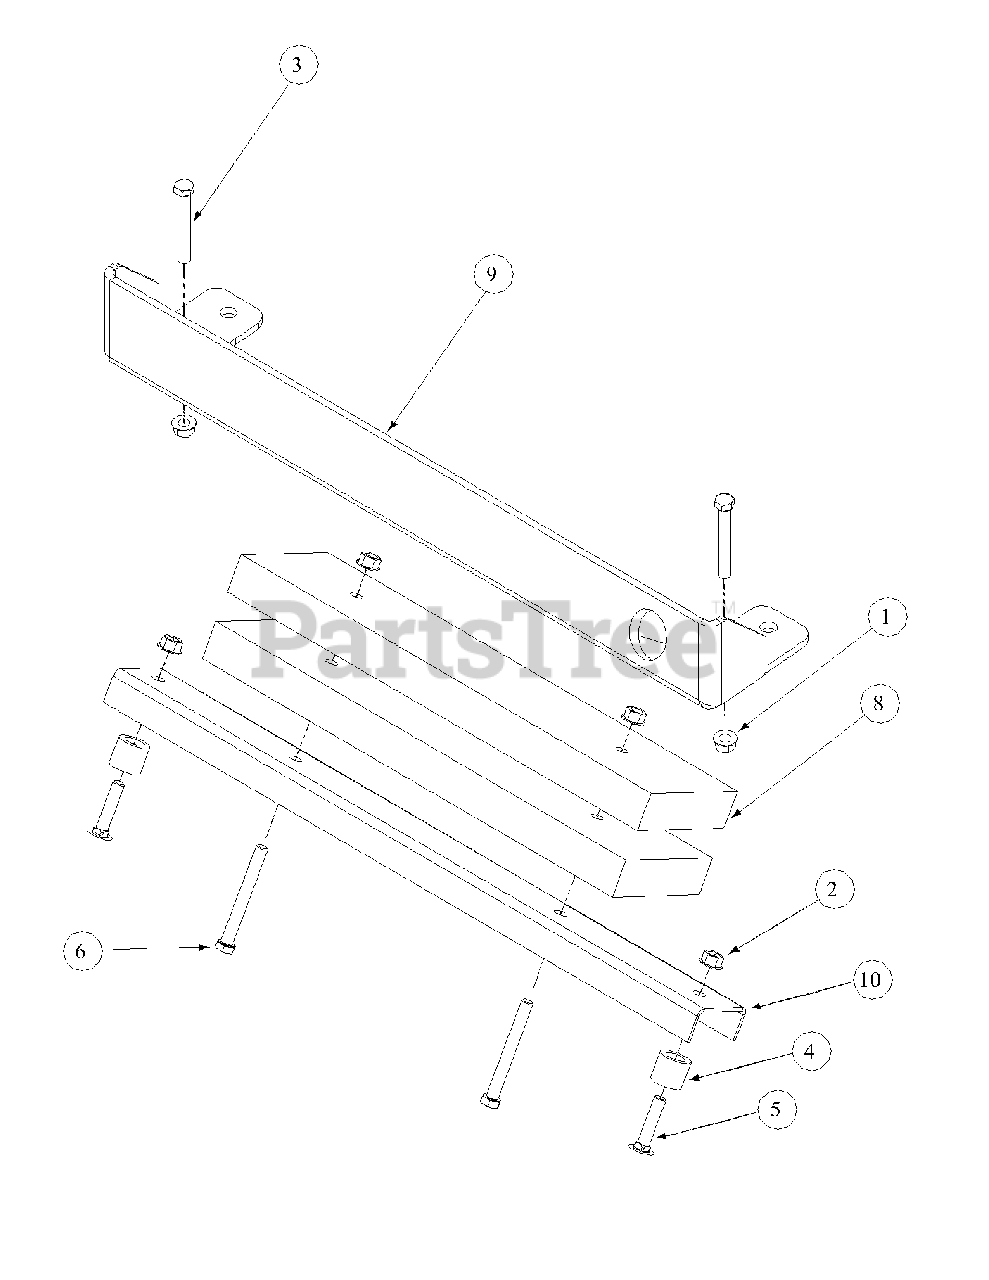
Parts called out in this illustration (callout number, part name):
1	Hex Nut, 1/2-13, Insert Lock
2	Nut, Hex 3/8-16 Flange Lock
3	HHCS, 1/2-13, 3.00
4	Spacer Crossbar
5	Carriage Bolt, 3/8-16, 1.75
6	HHCS, 3/8-16, 3.25
9	Rear Bumper Plate
10	Bumper Cross Bar-Rear
